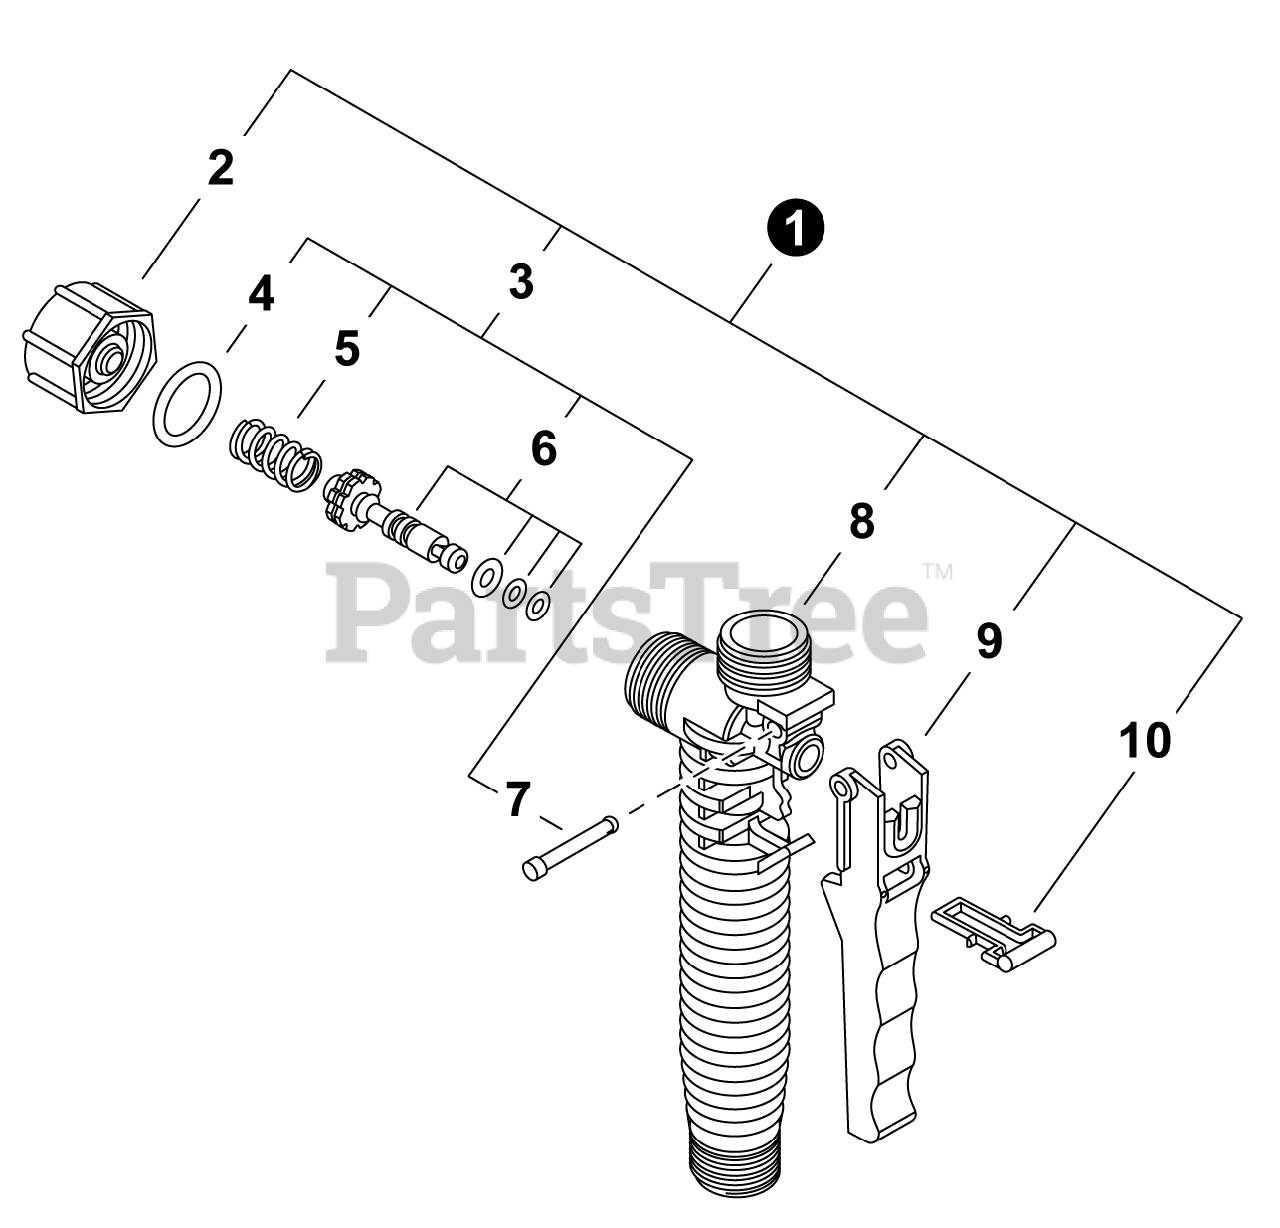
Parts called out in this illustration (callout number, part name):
1	GUN, SPRAY
2	CAP, DISCHARGE
3	REPAIR KIT, DISCHARGE
4	O-RING, DISCHARGE
5	SPRING, DISCHARGE
6	SPOOL ASSY
7	PIN, TRIGGER
8	BODY, SPRAY GUN
9	LEVER, TRIGGER
10	LOCK, TRIGGER
